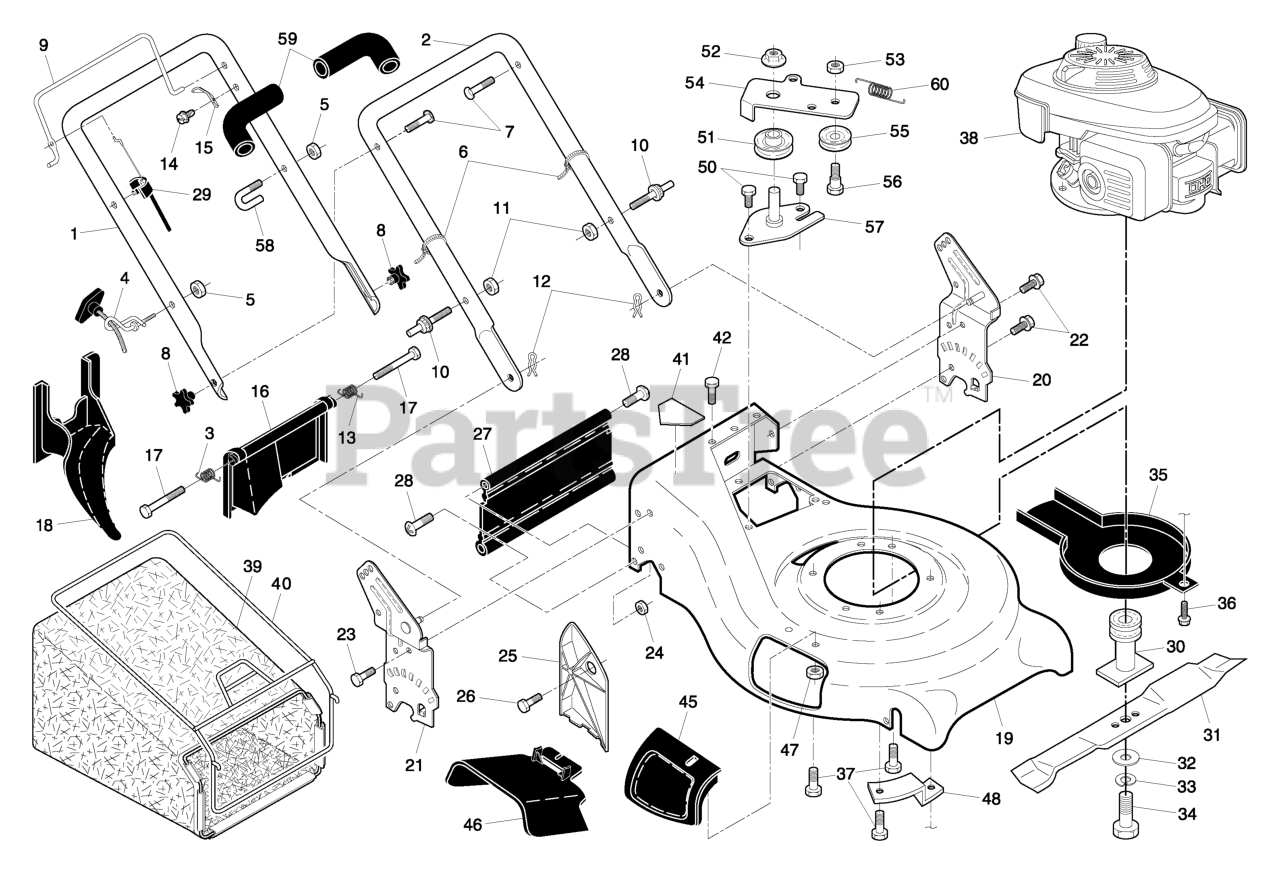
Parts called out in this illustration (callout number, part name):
1	HANDLE.ASM.UP.OFF/EZ.CR.W/GRIP
2	HANDLE.LOWER.21.GREY
3	SPRING.LH.REAR.DOOR.21.RWGD
4	RB GUIDE.ROPE.STD.BLK.ZIN WSL
5	NUT
6	TIE GUIDE
7	BOLT, HANDLE 5/16-18X1.75
8	KNOB.HANDLE.STAR.HUSQ.GRAY
9	BAIL.DSTRT.FL.AW.CREAS.ORANGE
11	NUT.CENTERLOCK.5/16-
12	HAIRPIN COTTER
13	SPRING.RH.REAR.DOOR.21.RWGD
15	BRACKET UPSTOP
16	DOOR.REAR.PLASTIC.21.RWGD.BLAC
18	PLUG.MULCHER.RGD.21.
19	RP KIT.HSG.21.RGD.MC.ORAN
20	BRKT.ASM.HNDL.21.RWGD.LT
21	BRKT.ASM.HNDL
22	SELF-TAPPING SCREW 5/16-18X3/4
23	BOLT, HEX HEAD 5/16-18
24	NUT.71038.31-18.HEX.NYLOCK
25	CLIPPING DEFLECTOR
27	SKIRT, REAR
28	HINGE SCREW
29	SNAP-ON.ZONE.CABLE.ASS
30	BLADE ADAPTOR / PULLEY
31	BLADE.21.PUSH/RWGD/FWG
32	WASHER,HARDEN
33	LOCKWASHER
34	SCREW, HEX HD 3/8-24 X 1-3/8
35	DEBRIS SHEILD
36	SCREW.HEX.WSH
37	BOLT 3/8-16X1-1/8
39	GBAG.44710247.SILVER.
40	FRAME.CATCHER.21.RGD.AG
41	DECAL HYT
45	MULCHER DOOR ASM.
46	DEFLECTOR, DISCHARGE
48	BRACKET
51	PULLEY.IDLER.V-BELT
52	NUT
53	LOCKNUT
54	IDLER ARM
55	IDLER PULLEY
56	SHOULDER BOLT
57	BRACKET.IDLER.ASM.EZ
59	GRIP.HANDLE.FOAM.WIDE.(1 SIDE)
60	SPRING, RETURN
